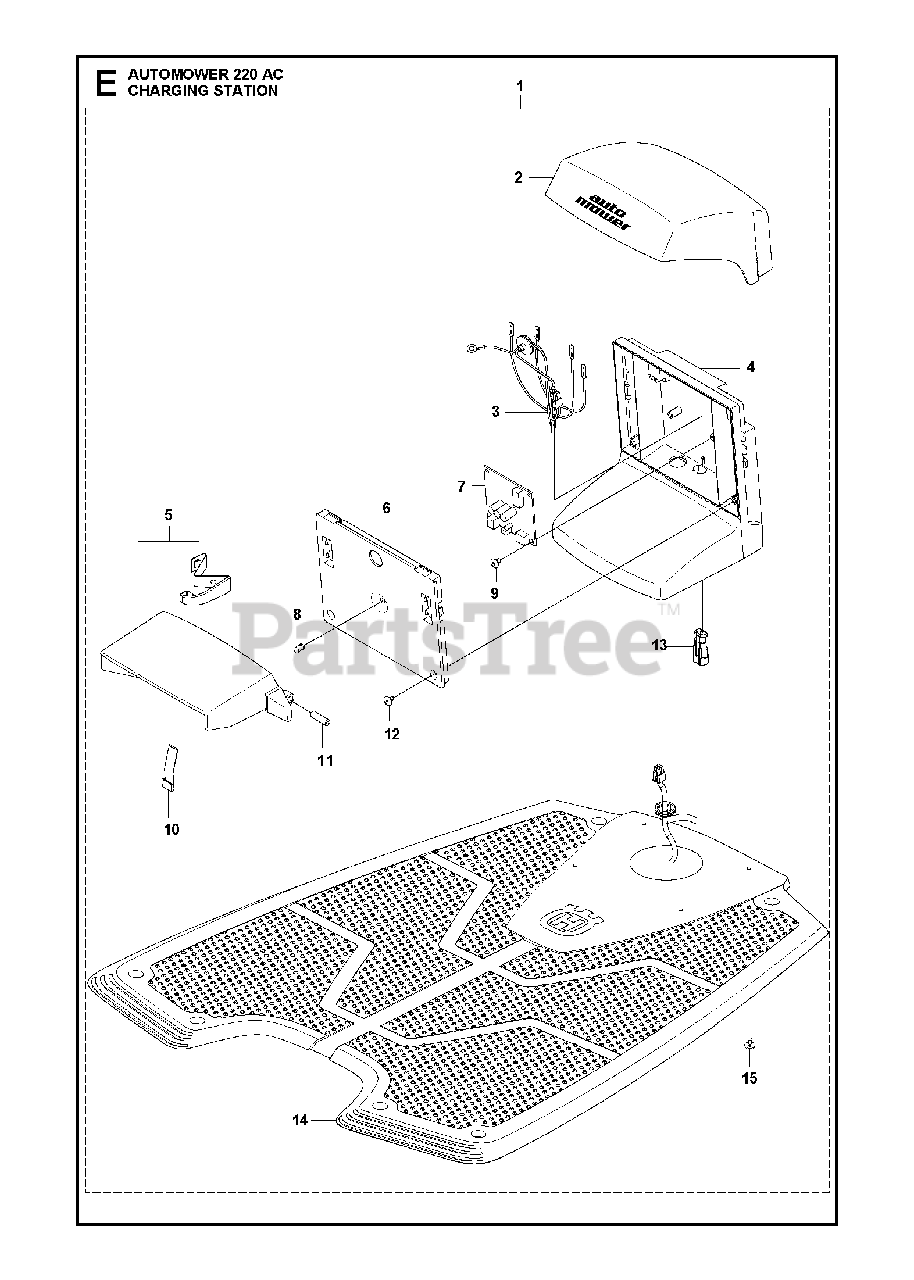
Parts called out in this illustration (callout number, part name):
1	CHARGING STATION
2	CS / TOWER COVER
3	WIRING ASSY LOOM
4	BODY CHARGING TOWER
5	KIT - CHARGING STATION
7	PRINTED CIRCUIT ASSY
8	LENS
9	SCREW SILVER 10MM
12	SCREW 14MM
14	CHARGING PLATE
15	SCREW 14MM
